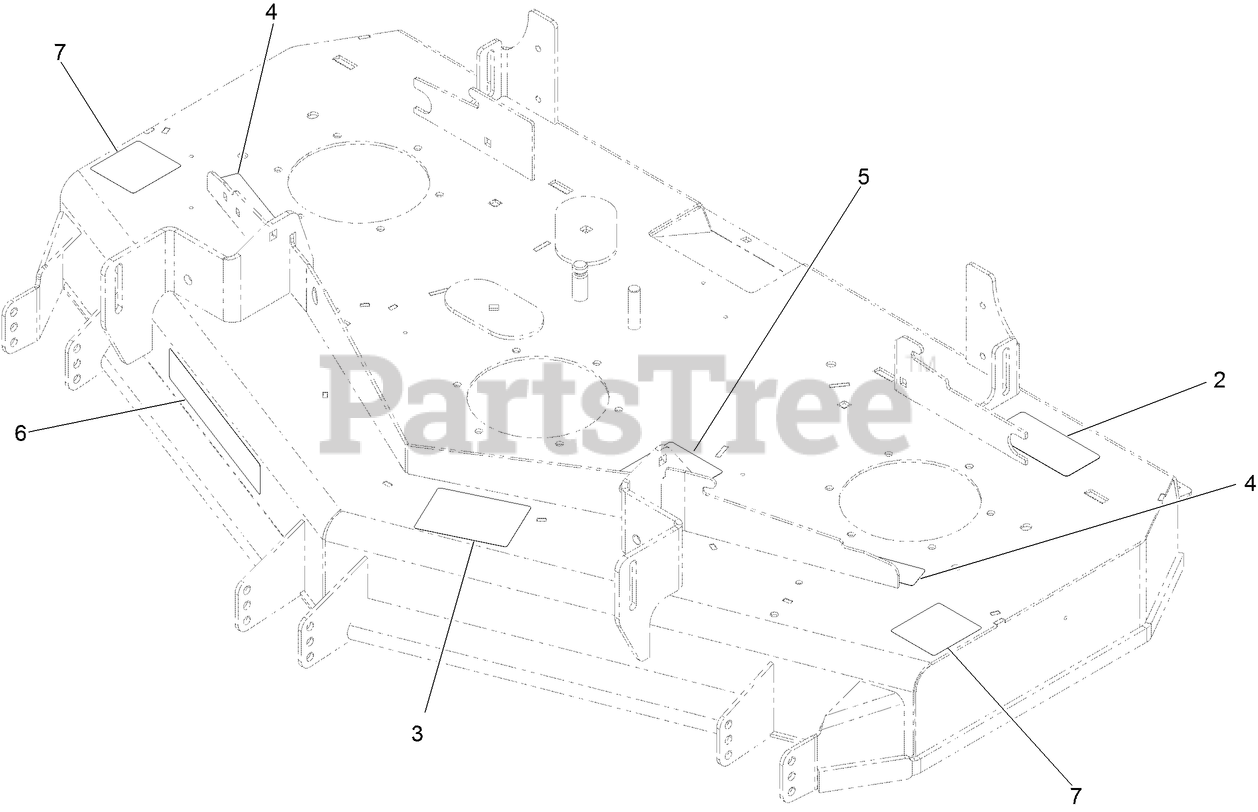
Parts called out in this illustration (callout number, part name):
2	DECAL-TORQUE, BLADE BOLT
3	DECAL-SCALP, ANTI
4	DECAL-COVER, MISSING
5	DECAL-ROUTING, BELT
7	DECAL-DANGER, THROWN OBJECT
